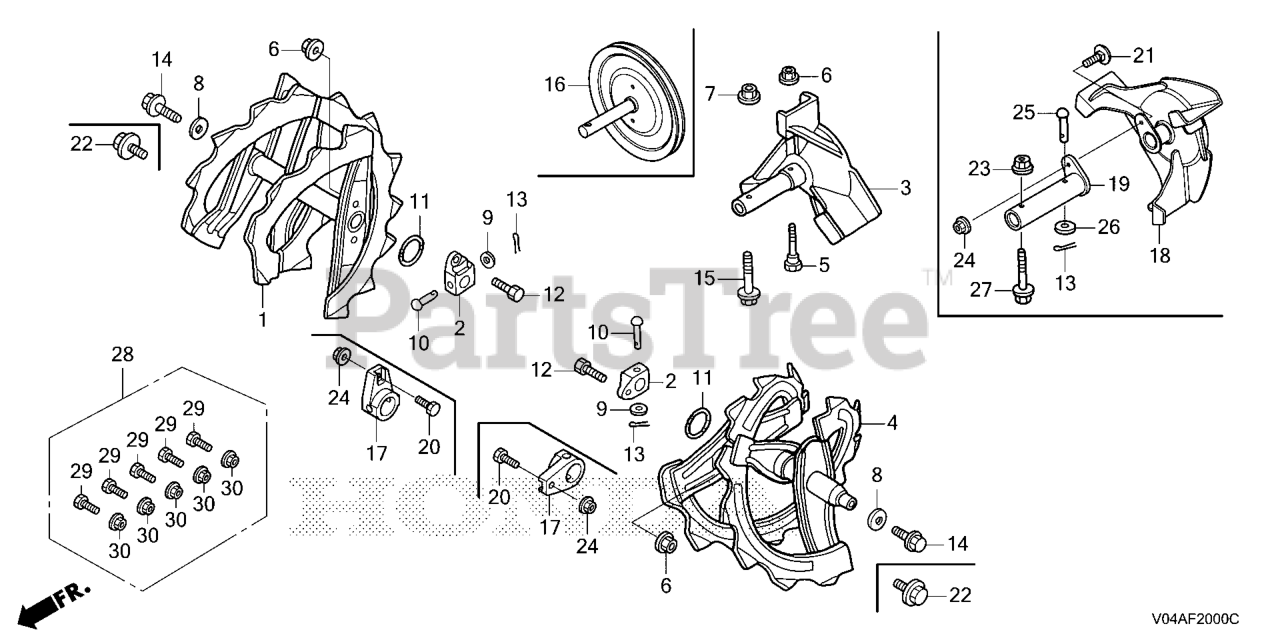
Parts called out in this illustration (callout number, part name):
2	BOSS, LOCK BOLT
9	WASHER, PLAIN (7MM)
10	PIN (7X40)
11	O-RING (18.23X1.9)
13	PIN, SPLIT (3.0X25)
13	PIN, COTTER (3.0X45)
16	PULLEY, DRIVEN
17	BOSS, LOCK BOLT
19	PIPE, JOINT
20	BOLT, SPECIAL (6X18)
21	BOLT, CARRIAGE (6X18)
22	BOLT, FLANGE (8X14)
23	NUT, FLANGE (8MM)
24	NUT, SELF-LOCK (6MM)
25	PIN (10X41)
26	WASHER, PLAIN (10MM)
27	BOLT, FLANGE (8X45)
28	BOLT KIT
29	BOLT, SPECIAL (6X18)
30	NUT, SELF-LOCK (6MM)
